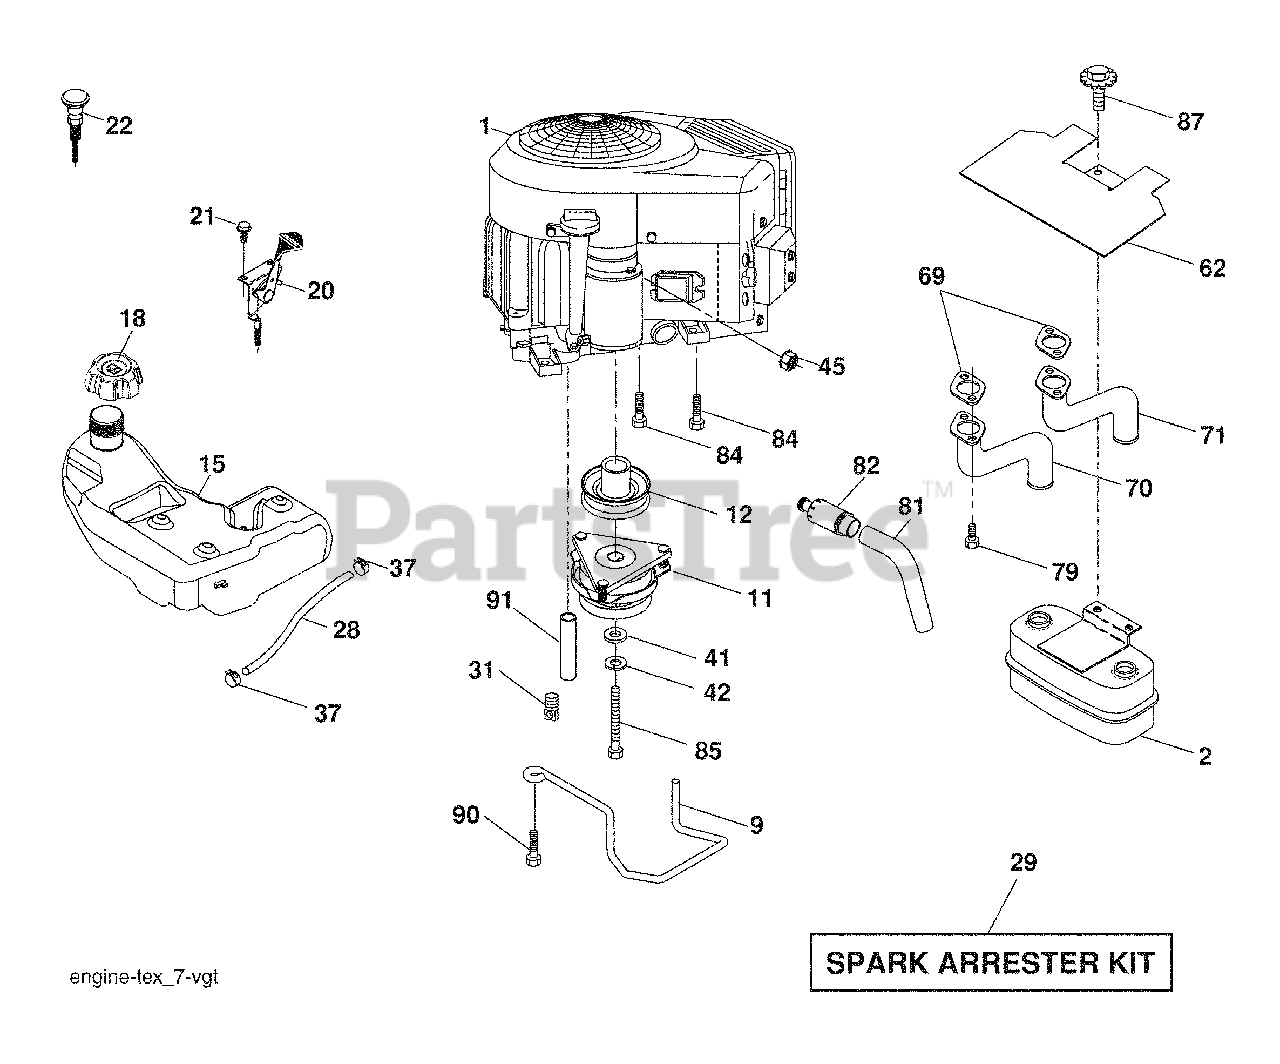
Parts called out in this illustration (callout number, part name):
9	Keeper Belt Engine
11	Clutch Electric
12	Pulley Engine
15	Tank Fuel 4.0
18	Cap Asm
20	Control Throttle
21	Screw #10 x .750 BOS Thread
22	Control Choke
28	Fuel Line
29	Spark Arrester Kit
31	Clip Push-In
37	Clamp Hose
41	Washer 1-1/2 OD x 15/32 ID x .250
42	Washer Lock 7/16
45	Nut Keps Hex 1/4-20 unc
62	Shield Heat Muffler
70	Tube Exhaust LH
71	Tube Exhaust RH
79	Screw Socket Head 5/16-18 x 1
81	Tube Drain Oil Easy
82	Plug Drain Oil
84	Screw 3/8-16 x 1-1/4
85	Bolt Hex 7/16-20 x 3.75 Gr. 5
87	Bolt 5/16-18 unc x 1 w/Sems
90	Screw 3/8-16 x 1
